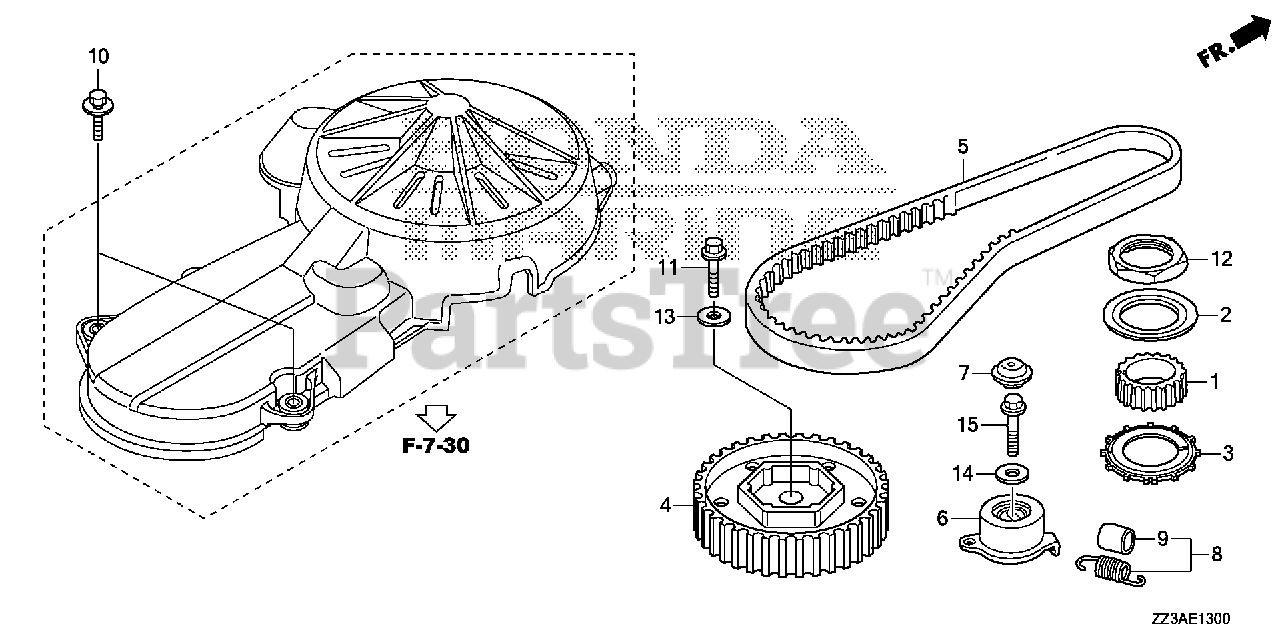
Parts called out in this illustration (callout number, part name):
1	PULLEY, TIMING BELT DRIVE (19T)
2	PLATE, TIMING BELT GUIDE
3	PLATE, CRANK PULSER
4	PULLEY, TIMING BELT DRIVEN (38T)
5	BELT, TIMING (88RU22.5 E-660)
6	TENSIONER, TIMING BELT
7	CAP, TIMING BELT TENSIONER
8	SPRING, TIMING BELT ADJUSTING
9	BOOT, SPRING
10	BOLT-WASHER (6X25)
11	BOLT, FLANGE (12X38)
12	NUT, LOCK (42MM)
13	WASHER (12.5X34X5)
14	WASHER, PLAIN (10MM)
15	BOLT, FLANGE (10X40)
